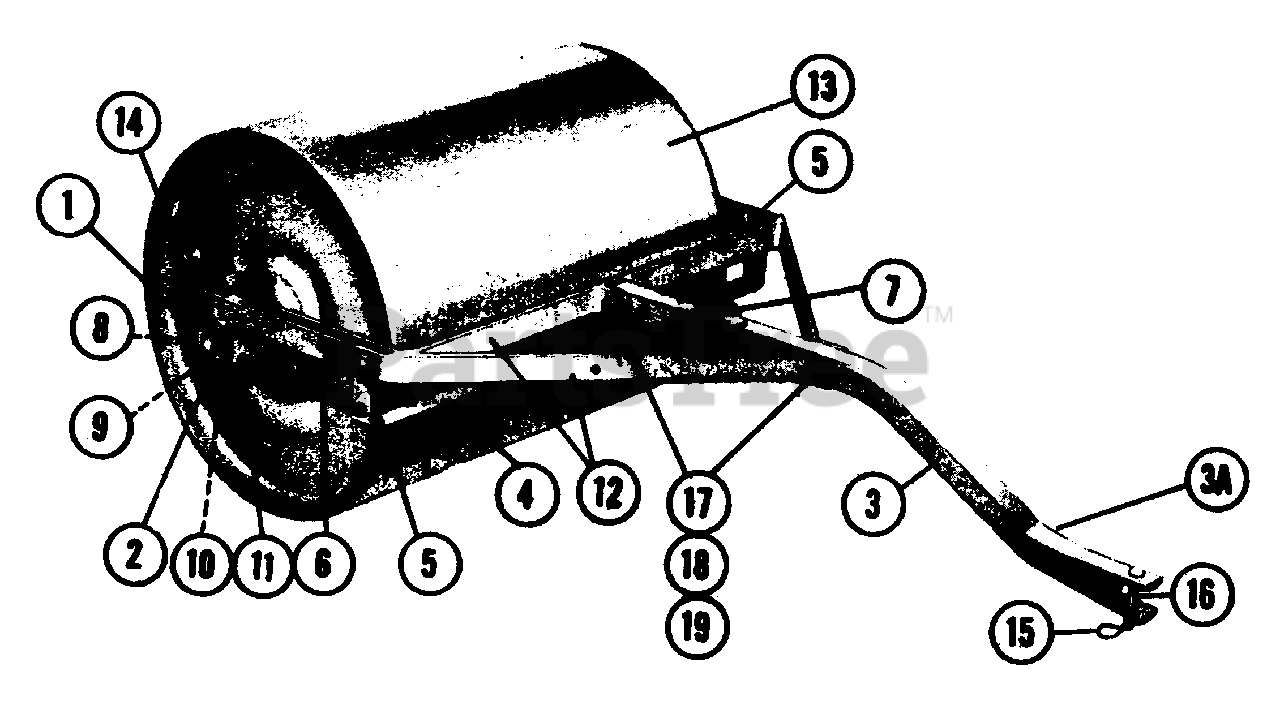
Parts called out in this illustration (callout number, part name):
1	Flat Washer 3/4"
7	BOX CATCH CLEVIS ASSEMBLY
8	Spring Clip
9	Nylon Bushing
10	Bearing Retainer
11	Extension Pin
12	Frame Assembly
13	Lawn Roller
14	Cotter Pin, 1/8 x 1 1/2"
15	Spring Clip
16	Pin
17	Hex Capscrew, 3/8-16 x 2 1/4
18	Lockwasher, 3/8"
19	Hex Nut. 3/8-16
